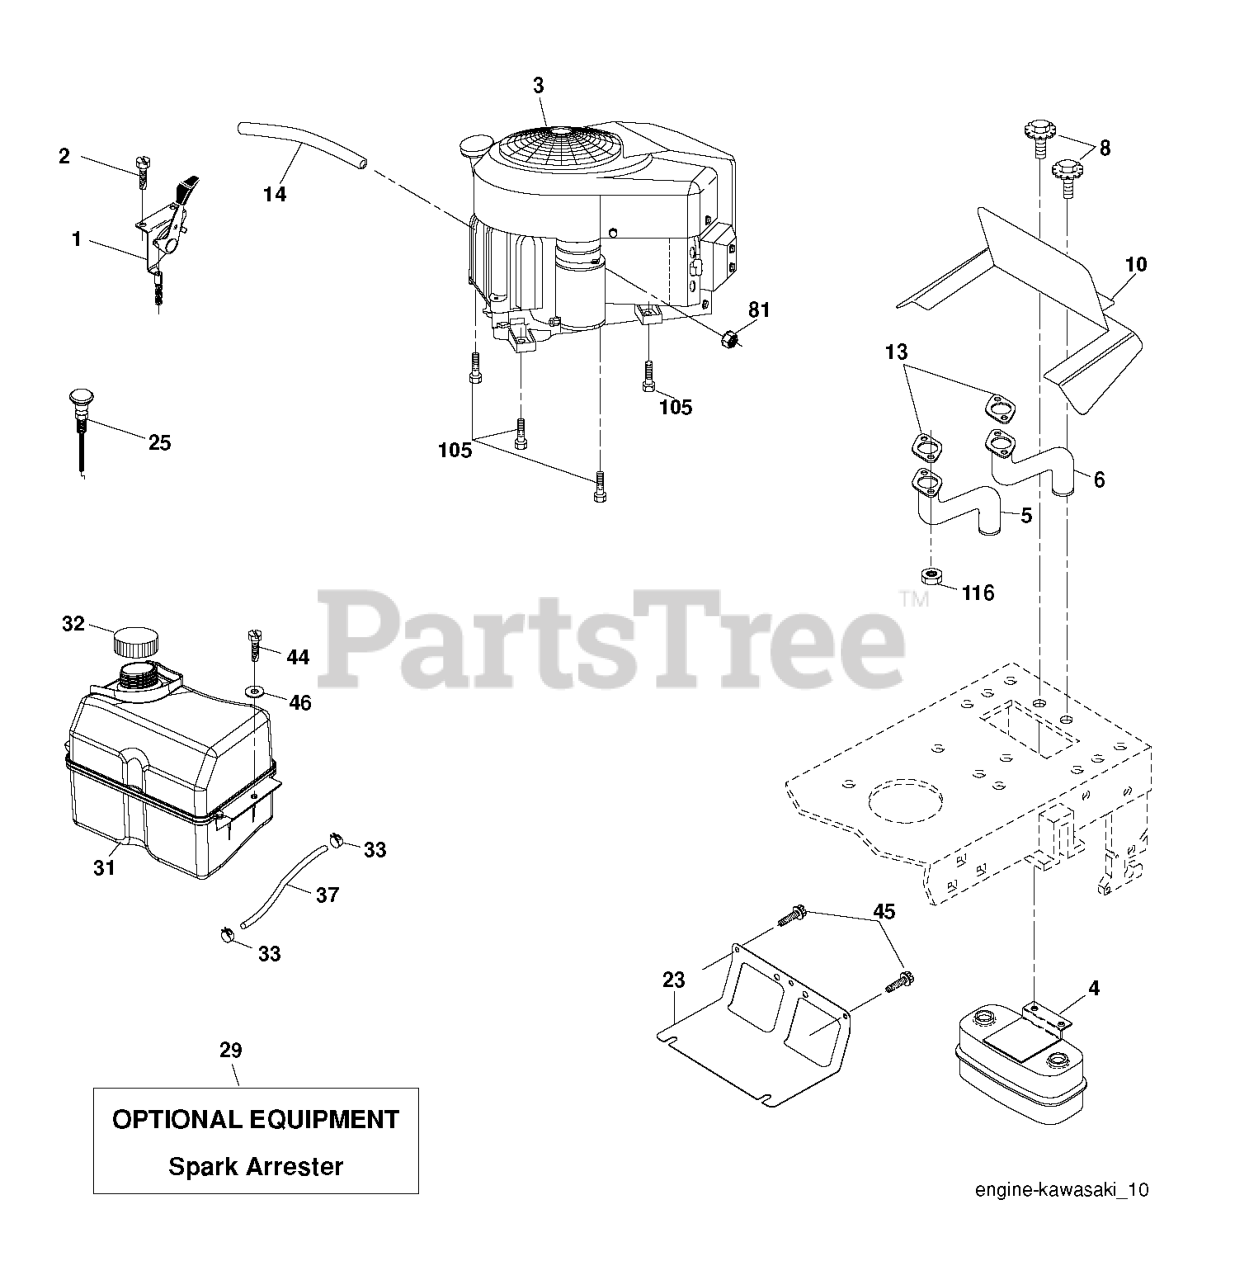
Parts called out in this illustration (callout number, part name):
1	CONTROL.THROTTLE.COBRA.BLACK
2	SCREW.#10 X 0.750.BOS
4	MUFFLER.TWIN.CYL.LOW.TONE
5	EXHAUST TUBE LH KAWI
6	EXHAUST TUBE RH KAWI
8	BOLT.5/16-18UNCX3/4 W/SEMS.BLK
10	RP SHIELD HEAT MUFFLER
13	GASKET.EXHAUST.KAWASAKI.15-1
14	TUBE, DRAIN OIL ASM.
23	SHIELD.BROWNING.DBR.GUARD
25	CONTROL.CHOKE.ERGO.PUSH-IN.BLA
29	KIT.SPARK ARRESTOR 794945 B&S
31	RP TANK FUEL FRT 1.5 GAL
32	FUEL CAP
33	HOSE CLAMP
37	LINE.FUEL.20
44	SCREW HEXWSHR 1/4-20X3/4
45	SCREW, 3/8-16X3/4
81	NUT
105	SCREW 3/8-16X1
116	NUT.HEX.FLANGE.TOPLOCK
